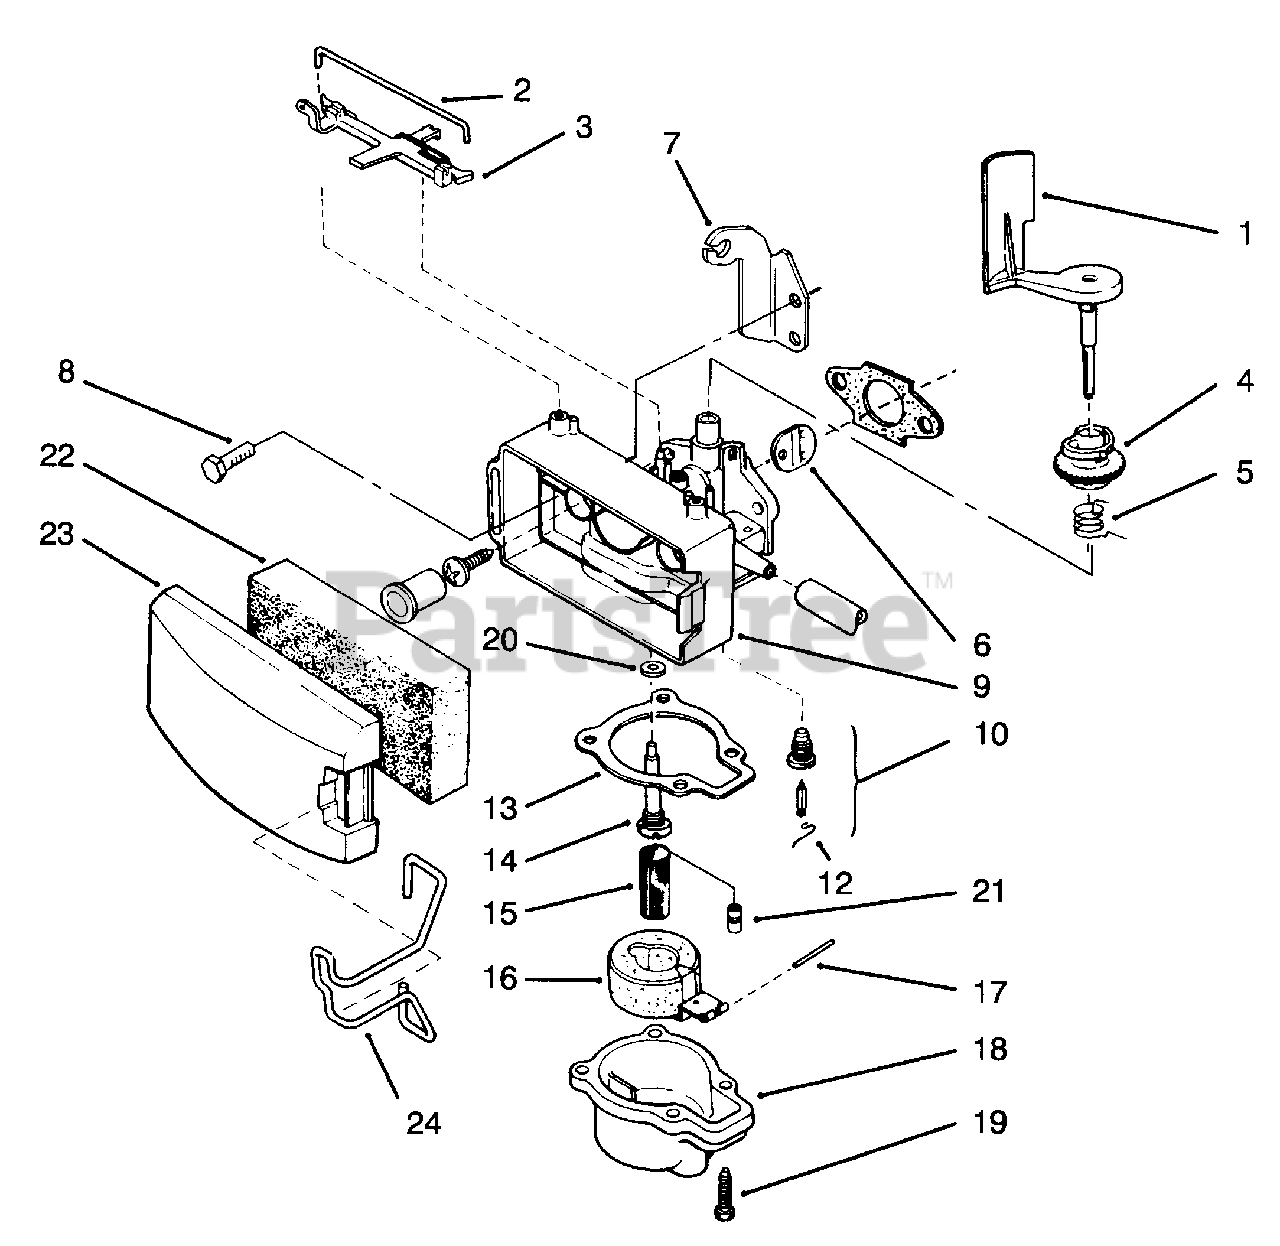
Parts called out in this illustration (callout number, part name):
1	Air Vane & Shaft
2	Retainer-Speed Control
3	Lever-Speed Adjust
4	Collar-Air Vane
5	Spring-Governor
6	Disc-Throttle
7	Bracket-Throttle Control
9	Carburetor Body
10	Kit-Float Valve, Body & Seat (Incl. Ref. #12)
12	Spring
13	Gasket
15	Filter-Fuel
16	Float & Arm Assembly
18	Float Chamber
21	Main Jet
22	Filter
23	Cover
24	Retainer
